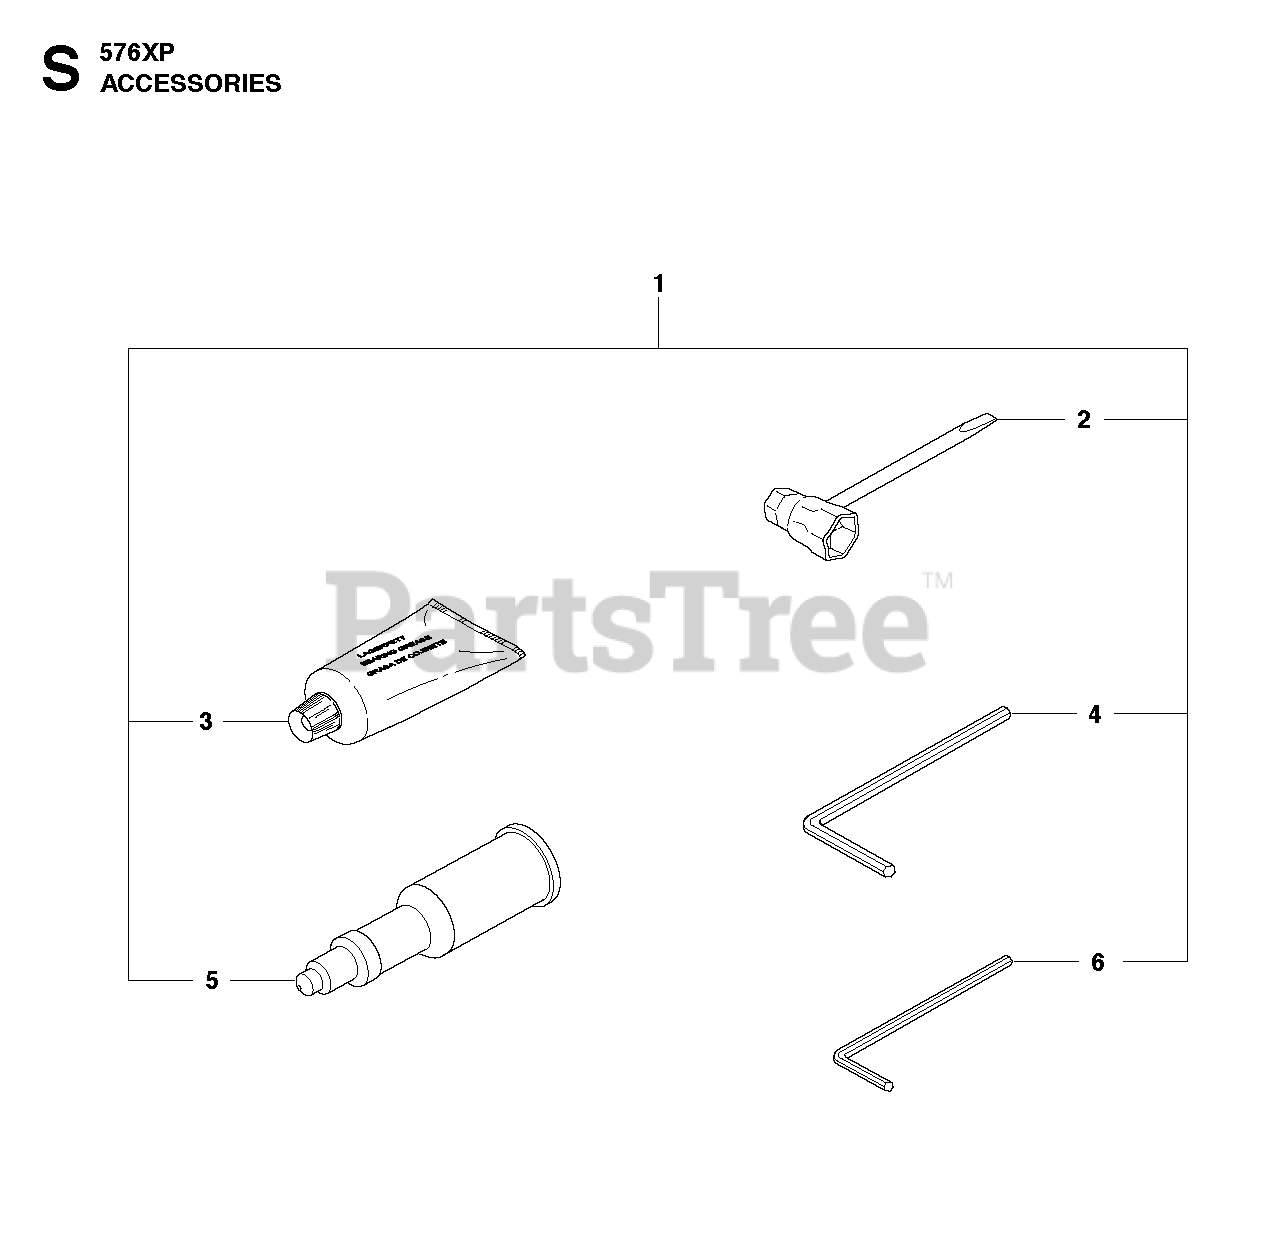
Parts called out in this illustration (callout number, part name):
1	TOOL KIT
2	COMBI TOOL
3	GREASE
4	L-SPANNER
5	Grease Gun
6	L-SPANNER
